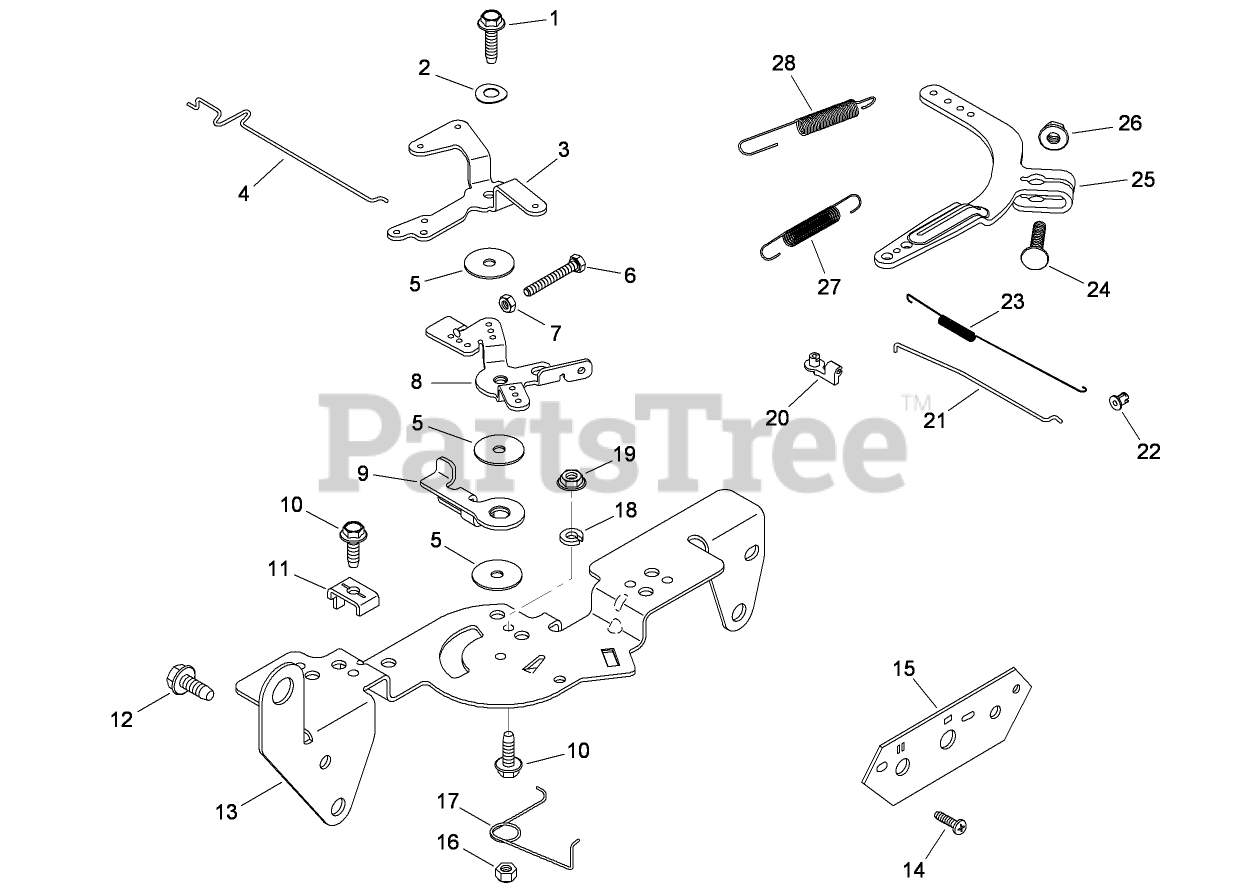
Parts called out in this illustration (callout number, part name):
1	SCREW-FLANGE, THREAD FORMING (M5X.8X20)
2	WASHER-SPRING (1/4)
3	LEVER-CHOKE
4	Linkage-Choke
5	WASHER-FLAT (5.5MM)
6	SCREW-SLOTTED HEAD (M4X0.7X25)
7	NUT (M4X0.7)
8	Lever-Control, Throttle
9	Lever-Actuator, Throttle
10	SCREW-FLANGE, THREAD FORMING (M5X0.8X16)
11	CLAMP-CABLE
12	SCREW-FLANGE, THREAD FORMING (M6X1.0X16)
13	Bracket-Control
14	SCREW-PPH (11-16X3/4)
15	PANEL-CONTROL, FRONT
16	NUT-LOCK (M5X.8)
17	SPRING-RETURN, CHOKE
18	Washer-Lock (.25)
19	Nut-HF (M5x0.8)
20	BUSHING-RETAINING, LINKAGE
21	Linkage-Throttle
22	BUSHING-LINKAGE, THROTTLE
23	SPRING-LINKAGE
24	BOLT-SQ NECK, RD HD (M6X1.0X25)
25	LEVER-GOVERNOR
26	NUT-FLANGE (M6X1.0)
27	Spring-Governor
28	Spring-Limiter, Throttle
